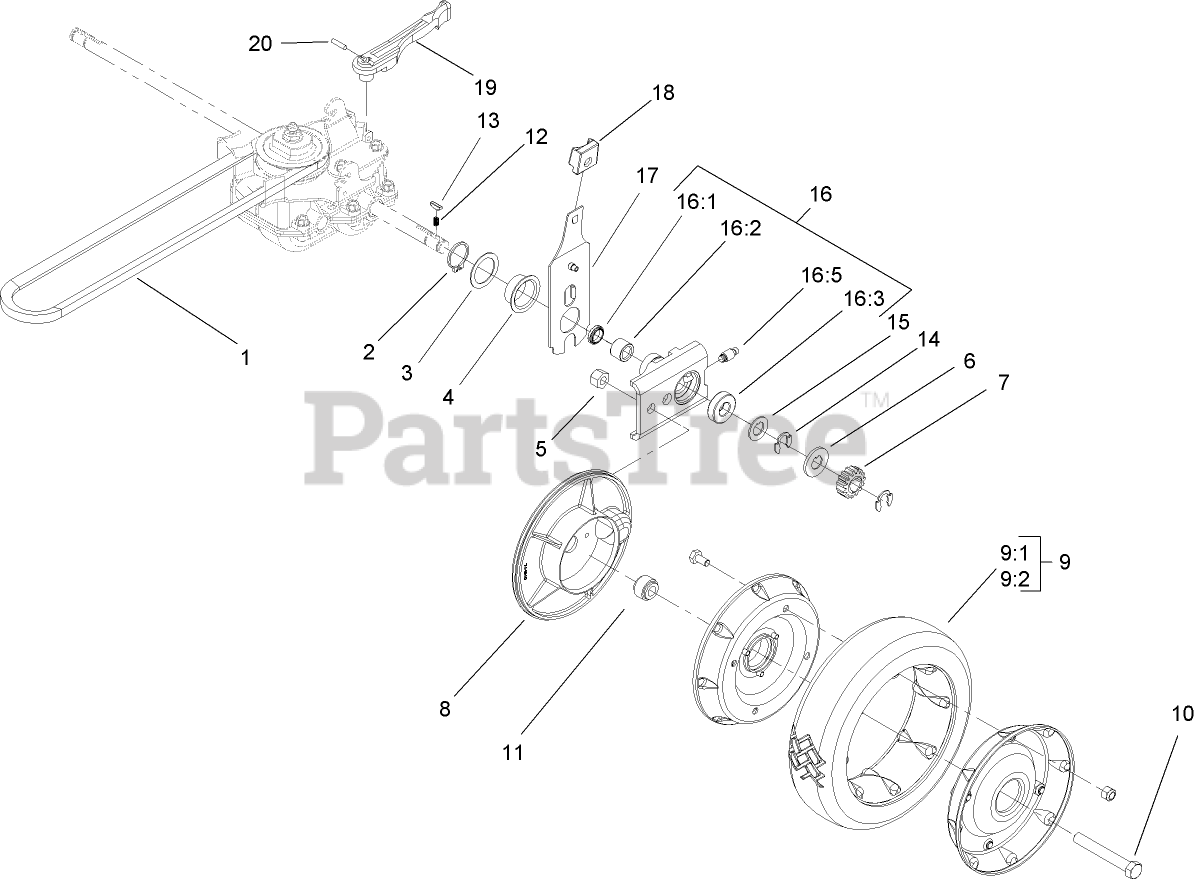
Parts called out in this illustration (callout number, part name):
1	V-BELT
2	RING-RETAINING
3	WASHER
4	CAP-END
5	NUT-LOCK, CONE
6	WASHER-THRUST, OUTER
7	GEAR-PINION
8	COVER-WHEEL
9:2	Wheel ASM
10	SCREW-HH
11	SPACER-COVER, WHEEL
12	SPRING-COMPRESSION
14	RING-RETAINING
15	WASHER-THRUST, OUTER
16	PIVOT ARM ASM
16:1	SEAL-OIL
16:3	BEARING-WHEEL
17	REAR SPRING ARM ASM
18	KNOB-ARM
19	LEVER-SHIFT
20	PIN-SPRING
